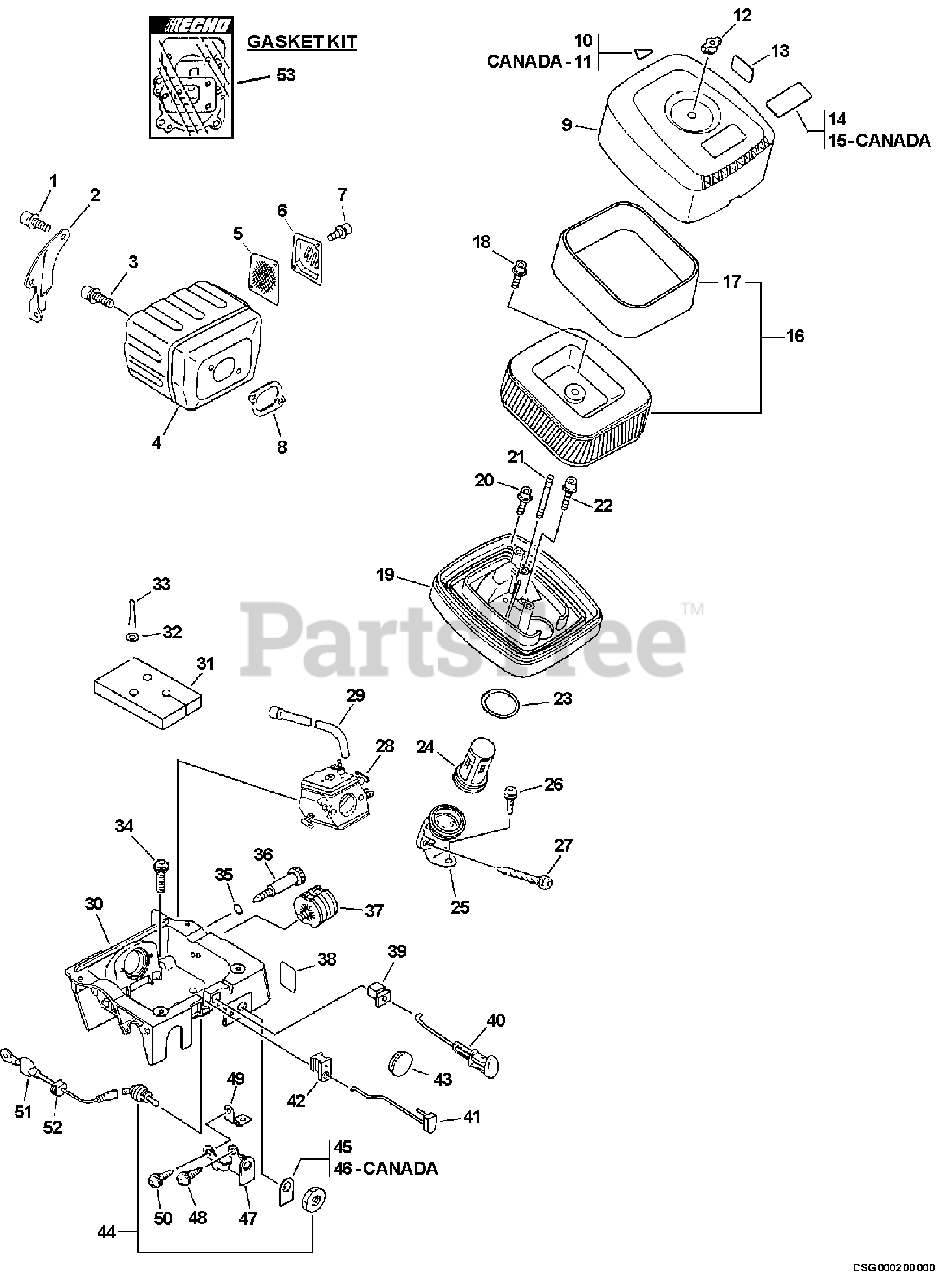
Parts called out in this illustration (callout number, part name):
1	SCREW - 5X14
2	BRACKET, MUFFLER
3	SCREW - 5X20
4	MUFFLER
5	SCREEN, SPARK ARRESTOR
6	GUIDE, EXHAUST
7	SCREW - 4X10
8	GASKET, EXHAUST
9	COVER, AIR FILTER
11	LABEL - FRONT
13	LABEL - CAUTION
14	LABEL - MODEL CSG-670
15	LABEL - MODEL CSG-670
16	FILTER, AIR
17	FILTER, AIR
18	SCREW - 5X16
19	CASE, AIR FILTER
20	SCREW - 5X16
22	SCREW - 5X25
24	SCREEN, DEBRIS
25	MOUNT, AIR FILTER
26	SCREW - 5X14
27	SCREW - 5X55
28	CARBURETOR HDA-166A
29	PIPE - IMPULSE
30	CASE, CARBURETOR
31	PAD, FOAM
33	PIN, SPLIT - 3X18
34	SCREW - 5X20
35	O-RING - 7
36	SCREW, IDLE ADJUST
38	LABEL - IDLE
40	ROD, CHOKE
41	ROD, THROTTLE
42	GUIDE, THROTTLE ROD
44	IGNITION SWITCH ASSY
45	LABEL - SWITCH
46	LABEL - SWITCH
47	BRACKET, SWITCH
48	SCREW - 5X10
49	TERMINAL - GROUND
50	SCREW - 4X10
51	LEAD - GROUND
53	GASKET KIT
